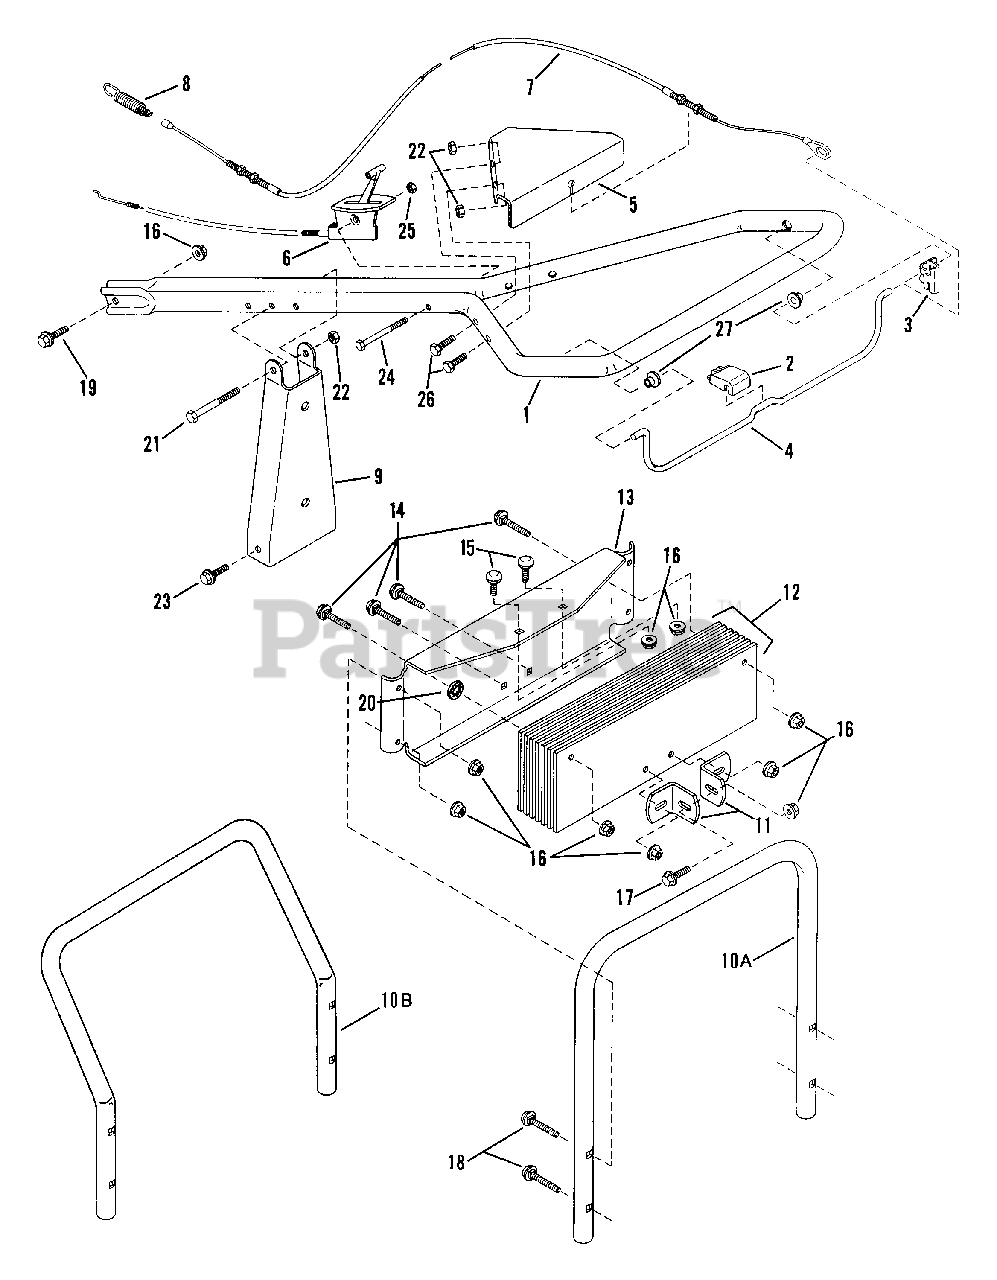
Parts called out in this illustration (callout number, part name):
1	BAR, Handle
2	COVER, Cable
3	CATCH, Bail
5	PANEL, Dash
6	CONTROL, Throttle (Series 0 & 1)
7	CABLE, Clutch
8	SPRING, Tine
9	SUPPORT, Handle
10A	BAR, Stand-Up (Briggs & Stratton)
10B	BAR, Stand-Up (Tecumseh)
11	BRACKET, Weight
12	WEIGHT, Steel
13	BOX, Weight
14	BOLT, 5/16-18 x 1 3/4" Carriage
15	BOLT, 5/16-18 x 5/8" Carriage
16	LOCKNUT, 5/16-18 Hex Flange
17	BOLT, 5/16-18 x 3/4" Hex Flange Lock
18	BOLT, 5/16-18 x 1 1/2" Carriage
19	BOLT, 5/16-18 x 1" Hex Flange Lock
20	RETAINER, 5/16 Bolt
21	SCREW, 5/16-18 x 2 3/4" Hex Head Cap
22	LOCKNUT, 5/16-18 Hex
23	SCREW, 5/16-18 x 3/4" Self-Tapping
24	SCREW, 1/4-20 x 2 3/4" Hex Head Cap
25	LOCKNUT, 1/4-20 Hex
26	SCREW, 5/16-18 x 1 1/2" Hex Head Cap
27	BUSHING
